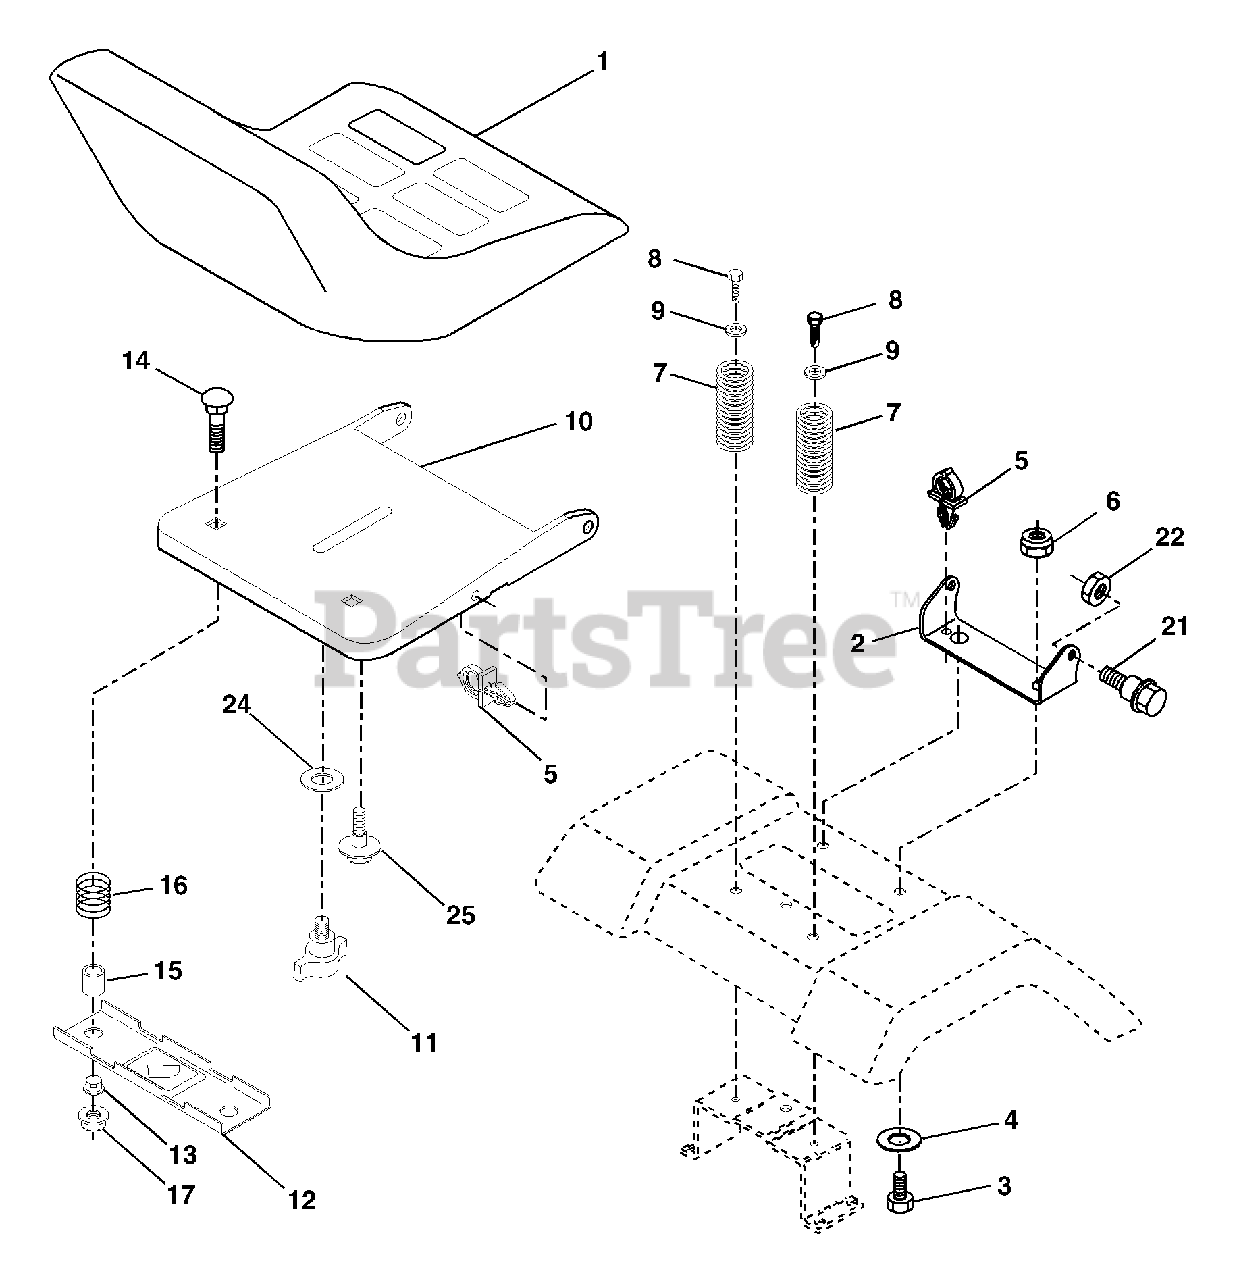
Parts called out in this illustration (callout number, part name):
1	Seat
2	Bracket Pivot Seat 8 720
3	Bolt Fin Hex 3/8-16 unc x 1
4	Washer 13/32 x 1 x 10 Ga.
5	Clip Push-In
6	Nut Hex w/Ins. 3/8-16 unc
7	Spring Seat Cprsn 2 250 Blk Zi
8	Screw 3/8-16 x 1-1/2 Smgml Tap/R Z
9	Washer 13/32 x 1 x 14 Ga.
10	Pan Seat
11	Knob Seat Adj. Wingnut
12	Bracket Mounting Switch
13	Bushing Snap Blk Nyl 50 Id
14	Bolt Rdhd Sqnk 1/4-2 x 1-1/2
16	Spring Cprsn
17	Nut Lock 1/4 Lge Flg Gr. 5 Zinc
21	Bolt Shoulder 5/16-18 unc-2a Blk DA
22	Nut Hex Lock W/Ins 5/16-18
24	Washer 17/32 x 13/16 x 12 Ga.
25	Bolt Shoulder 5/16-18 x 62
